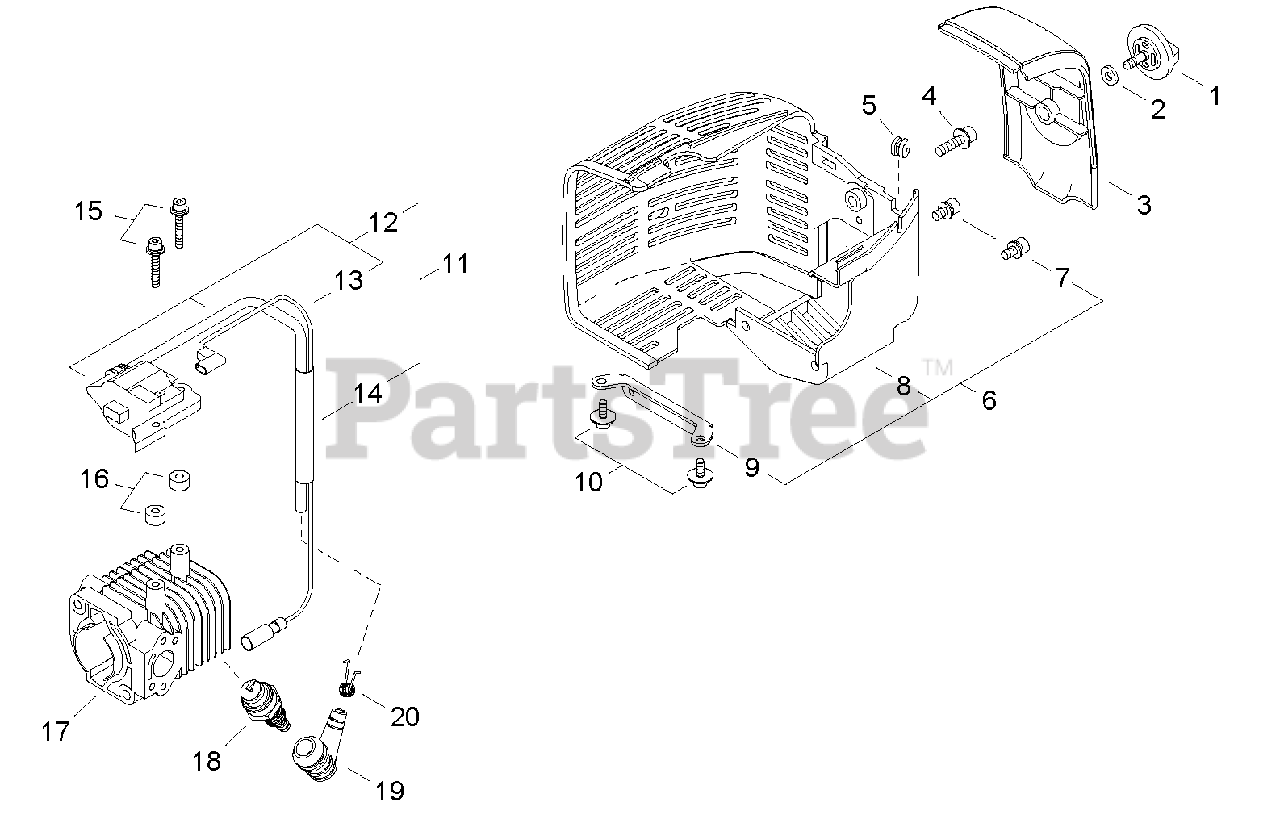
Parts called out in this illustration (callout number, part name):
1	THUMBSCREW
2	WASHER - VINYL
3	COVER, SPARK PLUG
4	SCREW - 5X20
5	GROMMET
6	ENGINE COVER KIT
7	SCREW - 5
8	COVER, ENGINE
9	BRACKET, ENGINE COVER
10	BOLT - 4
11	IGNITION COIL ASSY
12	IGNITION COIL ASSY
13	LEAD - IGNITION
14	TUBE, INSULATOR
15	SCREW - 4X26
16	INSULATOR
17	CYLINDER
18	SPARK PLUG -- BPMR-6A
19	CAP, SPARK PLUG
20	TERMINAL, SPARK PLUG CAP
